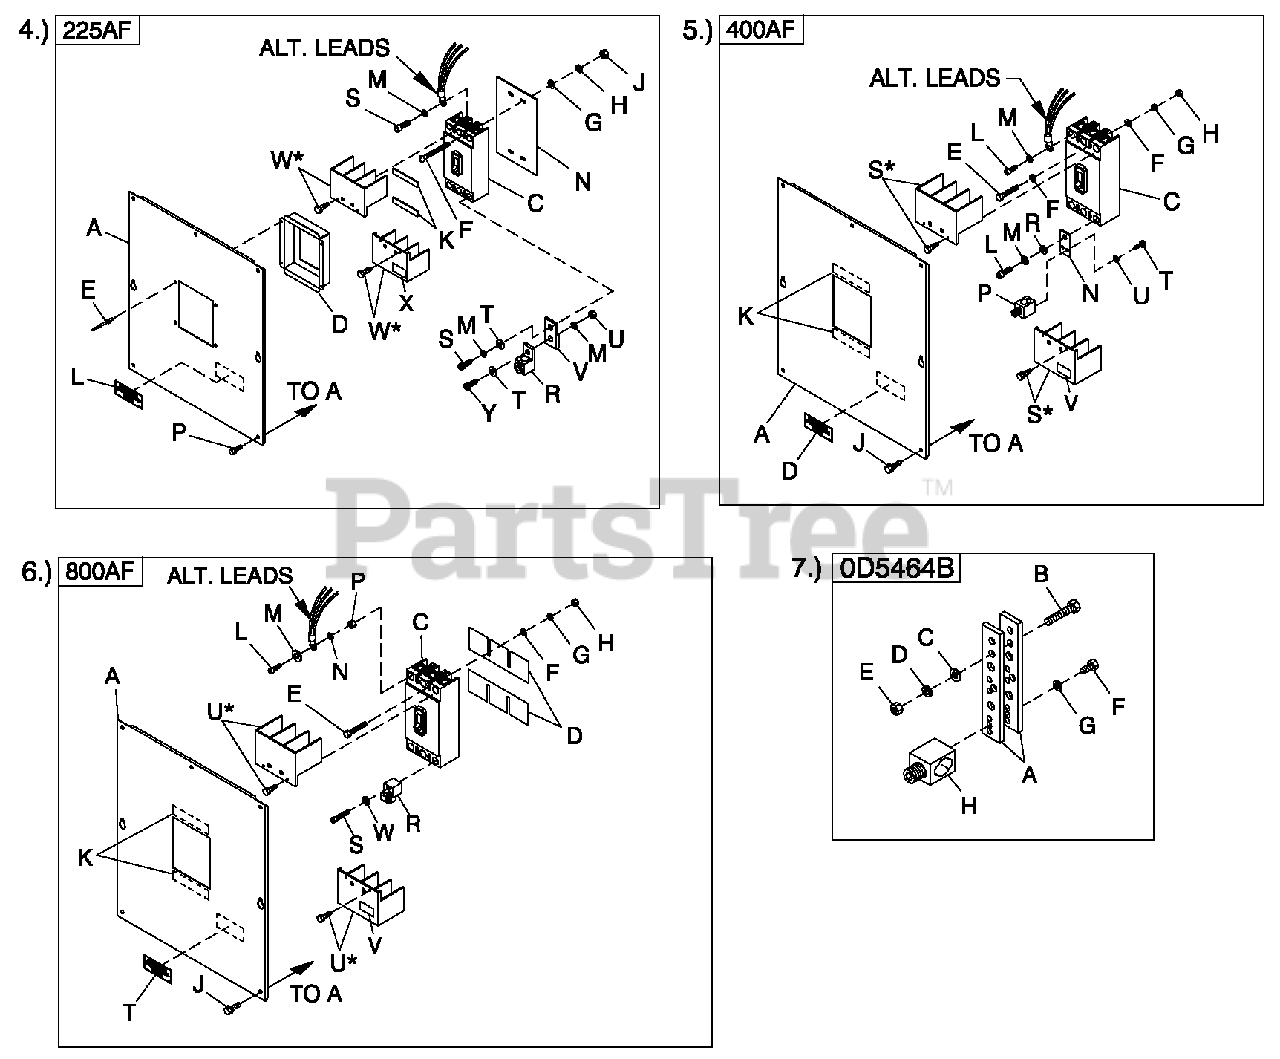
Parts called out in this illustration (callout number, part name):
A	COVER CBC5 225AF
C	CIRCUIT BREAKERS 200A FRAME
D	COVER CB DISH 225AF
E	RIVET POP .125 X .275 SS
F	SCREW RHM #8-32 X 3-1/4
G	WASHER FLAT #8 ZINC
H	WASHER LOCK #8-M4
J	NUT HEX #8-32 STEEL
K	TAPE ELEC 1/2 FOAM
L	DECAL CUSTOMER CONNECT INSIDE
M	WASHER LOCK M8-5/16
N	INSULATOR CB 225AF
P	SCREW THF M6-1 X 16 N WA Z/JS
R	LUG SLDLSS 300 MCM-6 AL/CU
S	SCREW SHC M8-1.25 X 20 G8
T	WASHER FLAT 5/16-M8 ZINC
U	NUT HEX M8-1.25 G8 CLEAR ZINC
V	BUS BAR 200A LUG ADAPTOR
W	TERMINAL COVER CB
X	DECAL TERMINAL SHOCK HZD BI
Y	SCREW SHC M8-1.25 X 25 G12.9
A	COVER CBC5 400AF
C	CIRCUIT BREAKERS 400A FRAME
D	DECAL CUSTOMER CONNECT INSIDE
E	SCREW RHM 10-32X4
F	WASHER FLAT #10 ZINC
G	WASHER LOCK #10
H	NUT HEX #10-32 STEEL
J	SCREW THF M6-1 X 16 N WA Z/JS
L	SCREW SHC M10-1.5 X 25 G12.9
M	WASHER LOCK M10
N	BUS BAR CB ADAPTER 225-400 A
P	LUG SLDLSS 600/250-1/0 X 1/4-28
R	WASHER FLAT 3/8-M10 ZINC
S	TERM COVER CB
T	SCREW HHC 1/4-28 X 1/2 G5
U	WASHER LOCK M6-1/4
V	DECAL TERMINAL SHOCK HZD BI
A	COVER CB C5 800AF
C	CIRCUIT BREAKERS 800A FRAME
D	INSULATOR CB 800AF
E	SCREW RHM 1/4-20 X 3-1/2
F	WASHER FLAT 1/4-M6 ZINC
G	WASHER LOCK M6-1/4
H	NUT HEX 1/4-20 STEEL
J	SCREW THF M6-1X16 N WA Z/JS
L	SCREW SHC M10-1.50X 40 G12.9
M	WASHER FLAT 3/8-M10ZINC
N	WASHER LOCK 3/8
P	NUT HEX M10-1.5 G8 YEL CHR
R	LUG SLDLSS 3/0-400X3 MCM AL/CU
S	SCREW SHC M6-1.0 X 50 G8.8
T	DECAL CUSTOMER CONNECT INSIDE
U	TERM COVER VITZROTECH 400AF CB
W	WASHER LOCK M6-1/4
A	BUS BAR NEUTRAL BLOCK 390
B	SCREW HHC M8-1.25 X 45 G8.8 FT
C	WASHER FLAT 5/16-M8ZINC
D	WASHER LOCK M8-5/16
E	NUT HEX M8-1.25 G8 YEL CHR
F	SCREW HHC 1/4-28 X 3/4 G5
H	LUG SLDLSS 600/250-1/0X1/4-28
